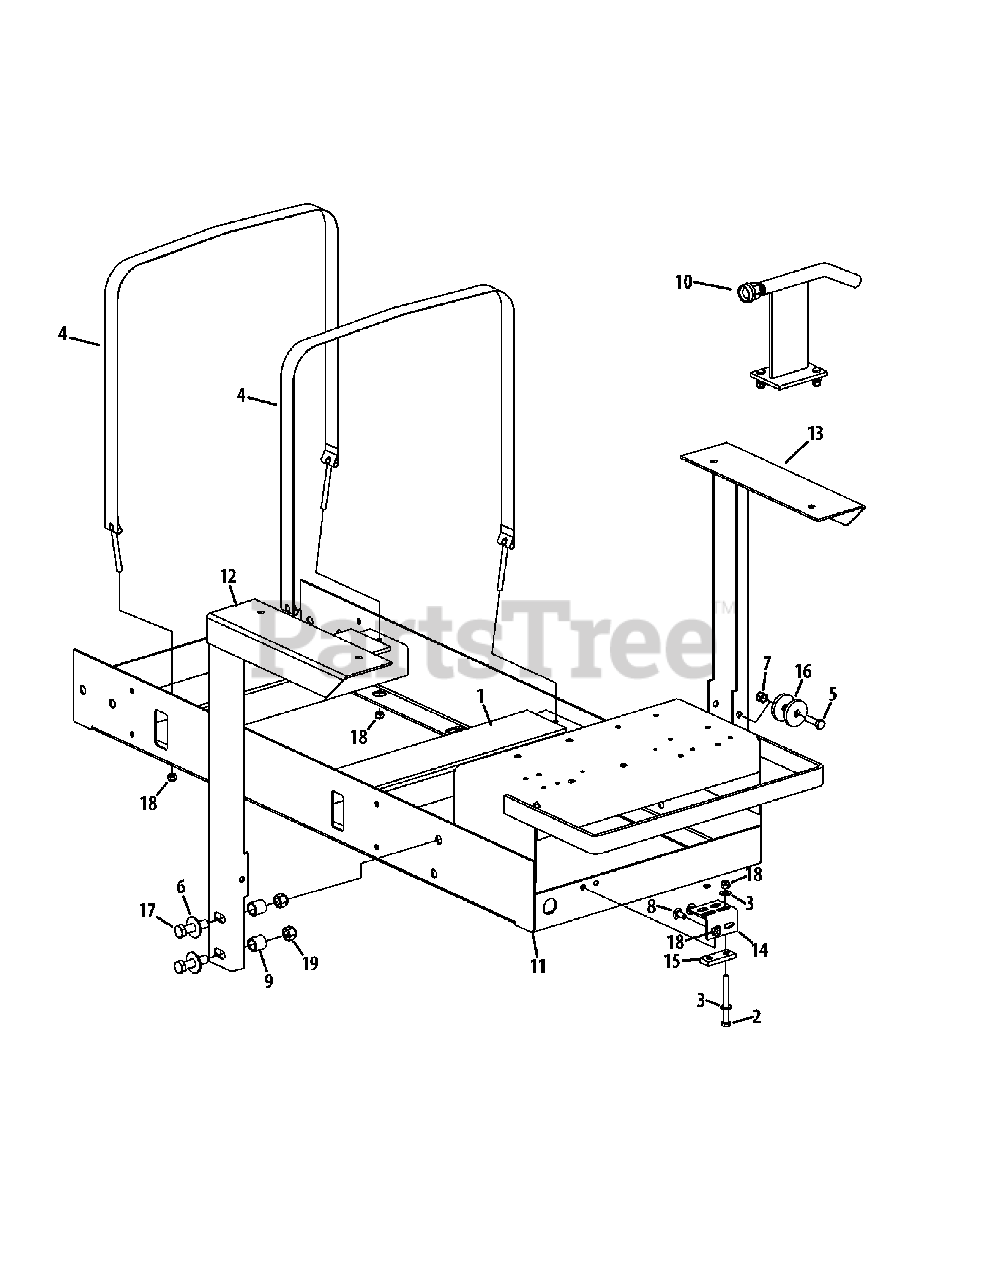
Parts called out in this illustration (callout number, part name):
1	Adhesive Backed Foam 4 x 1/4
2	Hex Screw, 5/16-18 x 3.25
3	Washer, .344 x .688 x .063
4	Tank Strap
5	Hex Screw, 3/8-16 x 1.25
6	Washer, .563 x 1.38 x .109
7	Lock Nut, 3/8-16
8	Carriage Bolt, 5/16-18 x .750
9	Spacer, .635 x .875 x .860
10	Air Gap Filler
11	Main Frame
12	LH Reel Support Assembly
13	RH Reel Support Assembly
14	Mounting Bracket
16	Washer, .438 x 1.745 x .250
17	Hex Screw, 1/2-13 x 2.00
18	Hex Lock Nut, 5/16-18
19	Hex Lock Nut, 1/2-13
